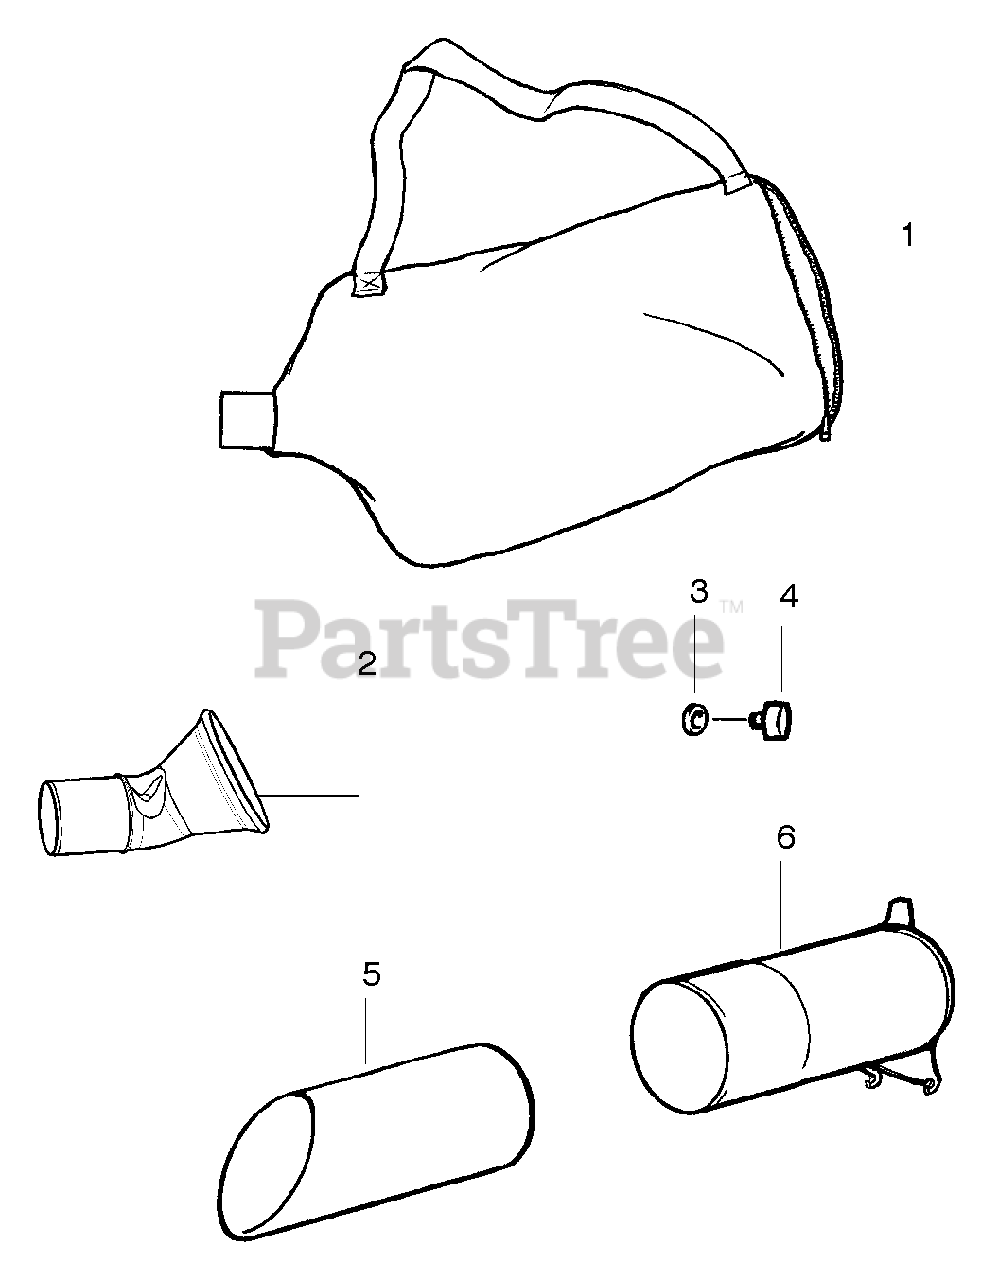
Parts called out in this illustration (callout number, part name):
1	Assy-Vac. Bag w/strap
2	Tube-Elbow Vac
3	Retainer-Vac Tube Knob
5	Tube-Lower Vac
6	Tube-Upper Vac
